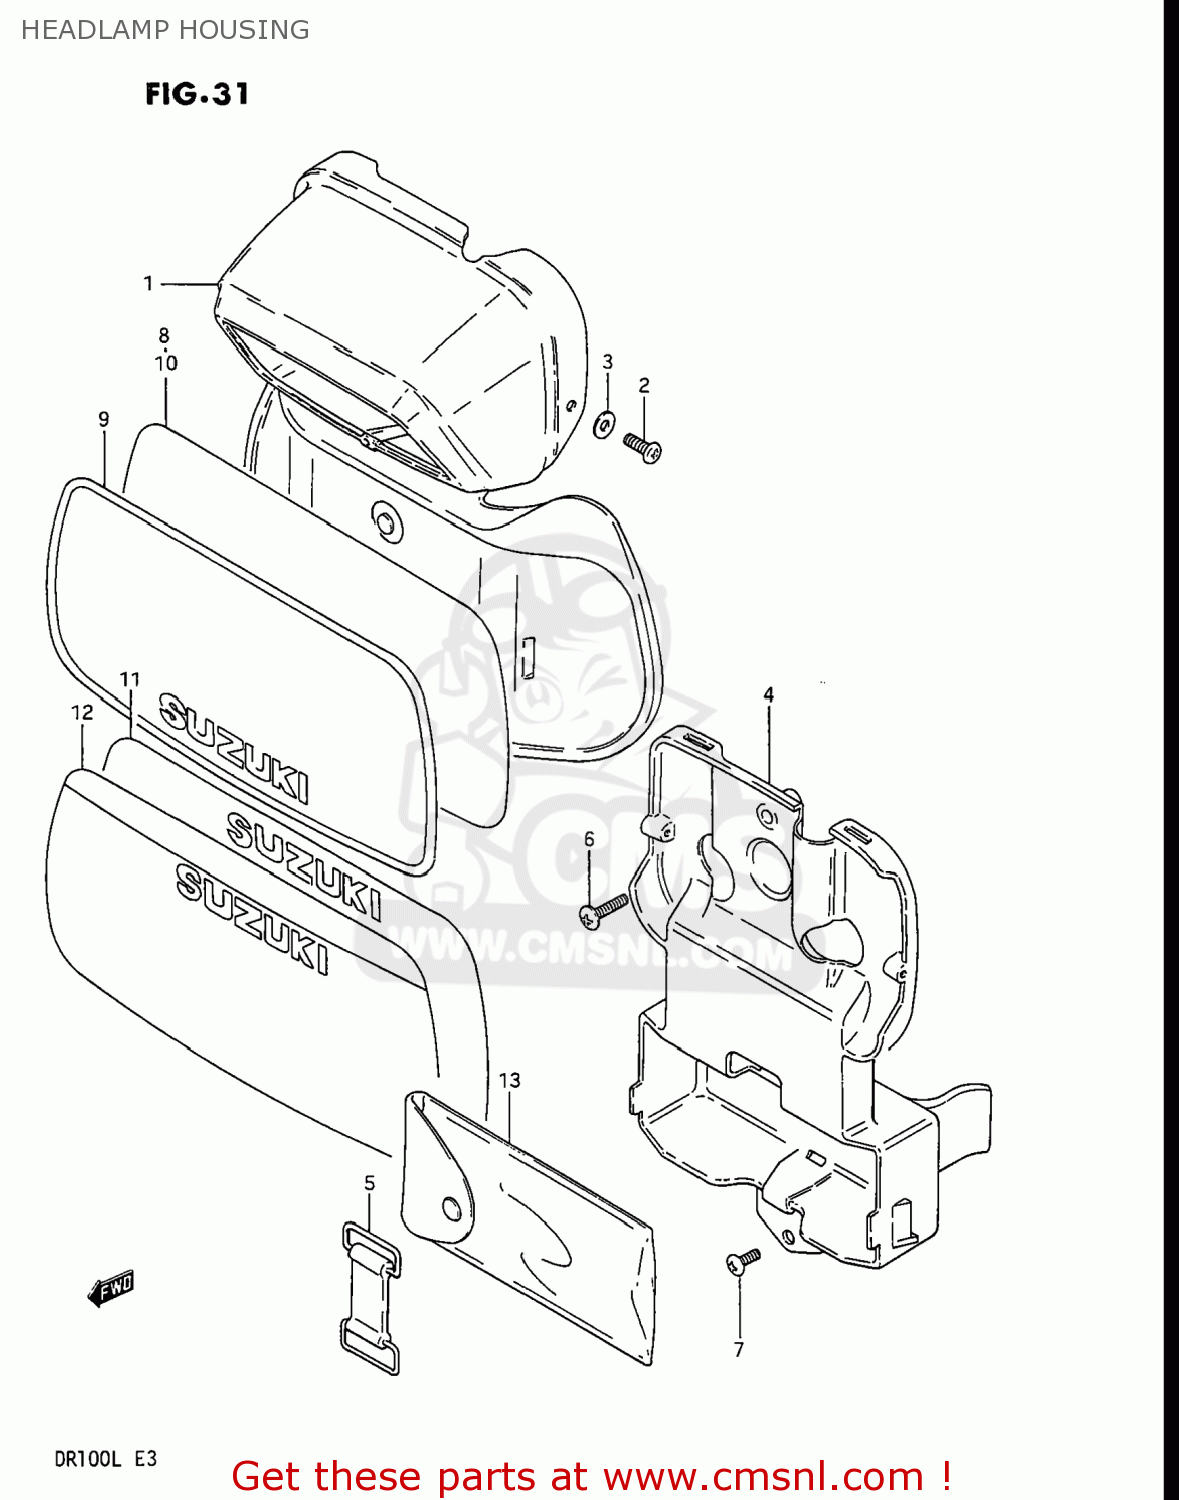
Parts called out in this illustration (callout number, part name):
1	HOUSING,HEADLAMP
2	TAPPING SCREW
3	WASHER 4MM
4	HOLDER,TOOL
5	BAND
6	SCREW
7	SCREW 6X12
8	EMBLEM,FRONT NUMBER PLATE
9	EMBLEM,FRONT NUMBER PLATE
10	EMBLEM,FRONT NUMBER PLATE
11	EMBLEM,FRONT NUMBER PLATE
12	EMBLEM,FRONT NUMBER PLATE
13	TOOL SET
